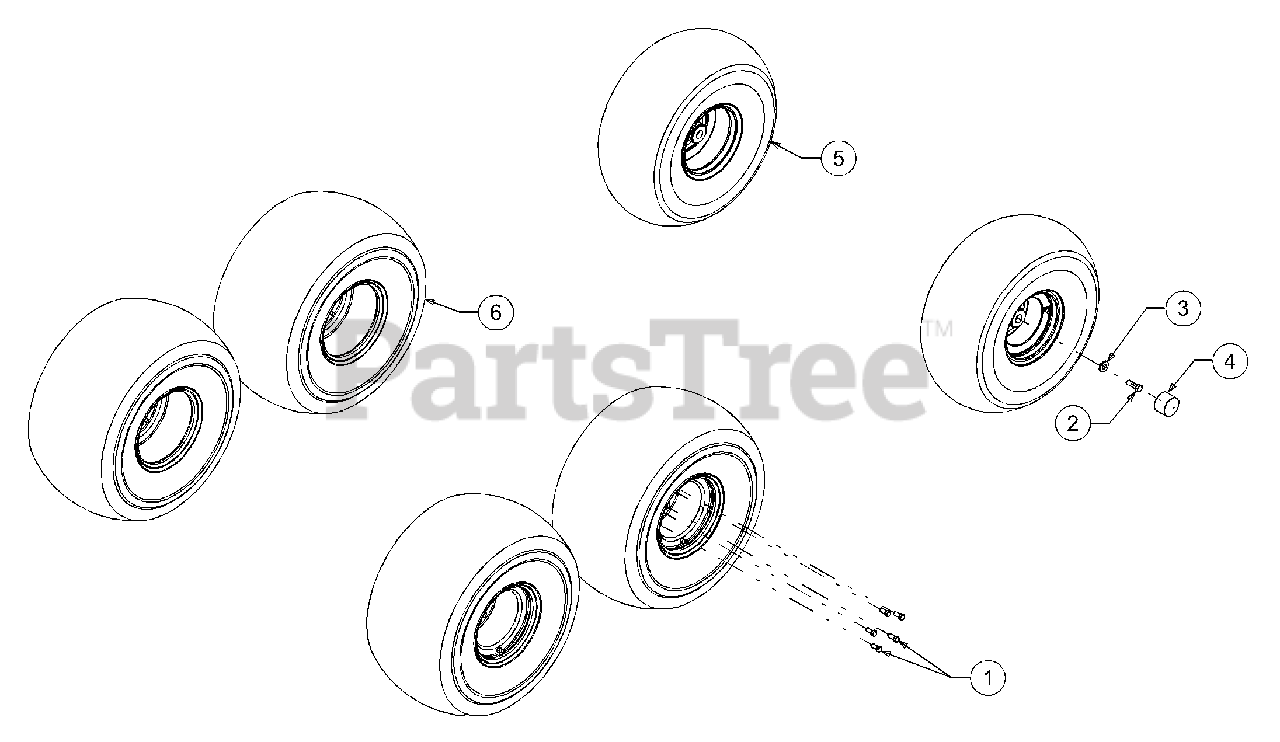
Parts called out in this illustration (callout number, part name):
1	Hex Screw, 7/16-20 x 1.5, Gr5
2	Hex Screw, 1/2-13 x 1.5, Gr5
3	Washer, Flat, .531 x 1.25 x .181
4	Dust Cover
5	Wheel Assembly, RH 22 x 11 x 10 (AT)
5	Wheel Assembly, LH 22 x 11 x 10 (AT)
6	Wheel Assembly, RH 25 x 11 x 10 (AT)
6	Wheel Assembly, LH 25 x 11 x 10 (AT)
